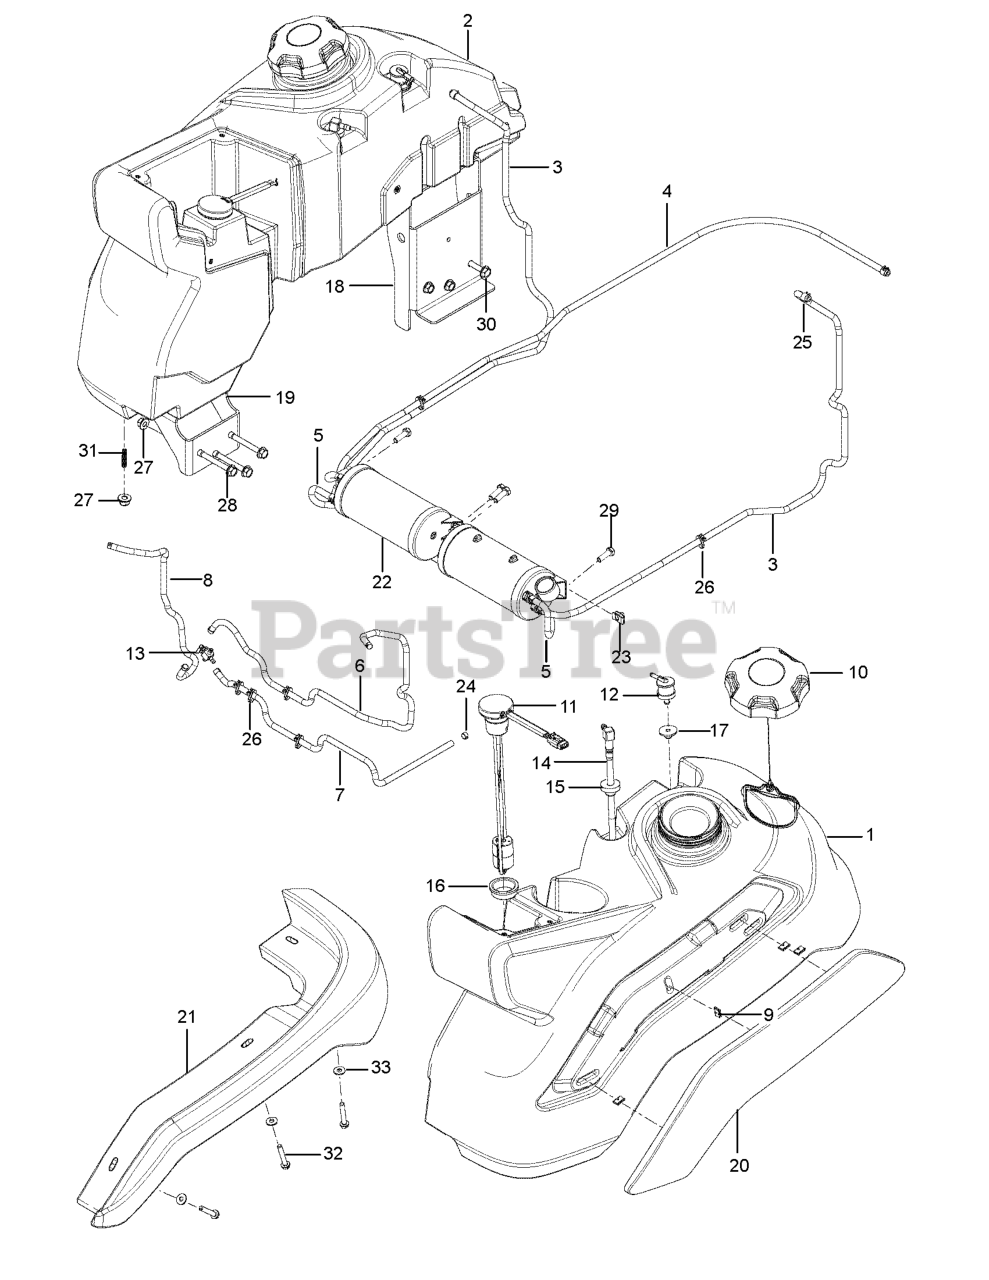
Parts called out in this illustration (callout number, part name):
1	FUEL.TANK.ASM.LH.PZ.REFRESH.18
2	FUEL.TANK.ASM.RH.PZ.REFRESH.18
3	HOSE.3/16".VAPOR.LINE.42"LGTH
4	HOSE.3/16".VAPOR.LINE.55"LGTH
5	HOSE 3/16" VAPOR LINE 13" LENG
6	HOSE.1/4".LOW.PERM.FUEL.LN.46"
7	HOSE.1/4".LOW.PERM.FUEL.LN.33"
8	HOSE.1/4".LOW.PERM.FUEL.LN.24"
9	Clip, U Type
10	CAP, FUEL
11	SENSOR.FUEL.LVL.FLOAT.V500
12	VALVE.FUEL.CHECK
13	FUEL VALVE
14	TUBE.ASM.FUEL.TANK.PICK-UP.LH
15	BUSHING OUTLET T
16	GROMMET, FUEL SENSOR
17	Check Fuel Grommet
18	BRACKET.FUEL.TANK.REAR.SUP.431
19	BRACKET.FUEL.TANK.REAR.SUP.431
20	Fuel Tank Cover, LH Console App
21	GUARD.MUD.LH
22	CANISTER.FLEX.6.3GAL3/16".TANK
23	1/4-20 U NUT
24	HOSE CLAMP
25	CLAMP, HOSE
26	TIE WRAP, 8-3/8", W/CLIP
27	5/16-18 NYLOC FLANGE NUT
28	BOLT HEX FLGHD 5/16-18X3 GR. 5
29	BOLT
30	SCREW
31	SCREW.5/16-18X1.25"THREADED
32	SCREW.1/4-20X1.5IN.HEX.MACH
33	WASHER
